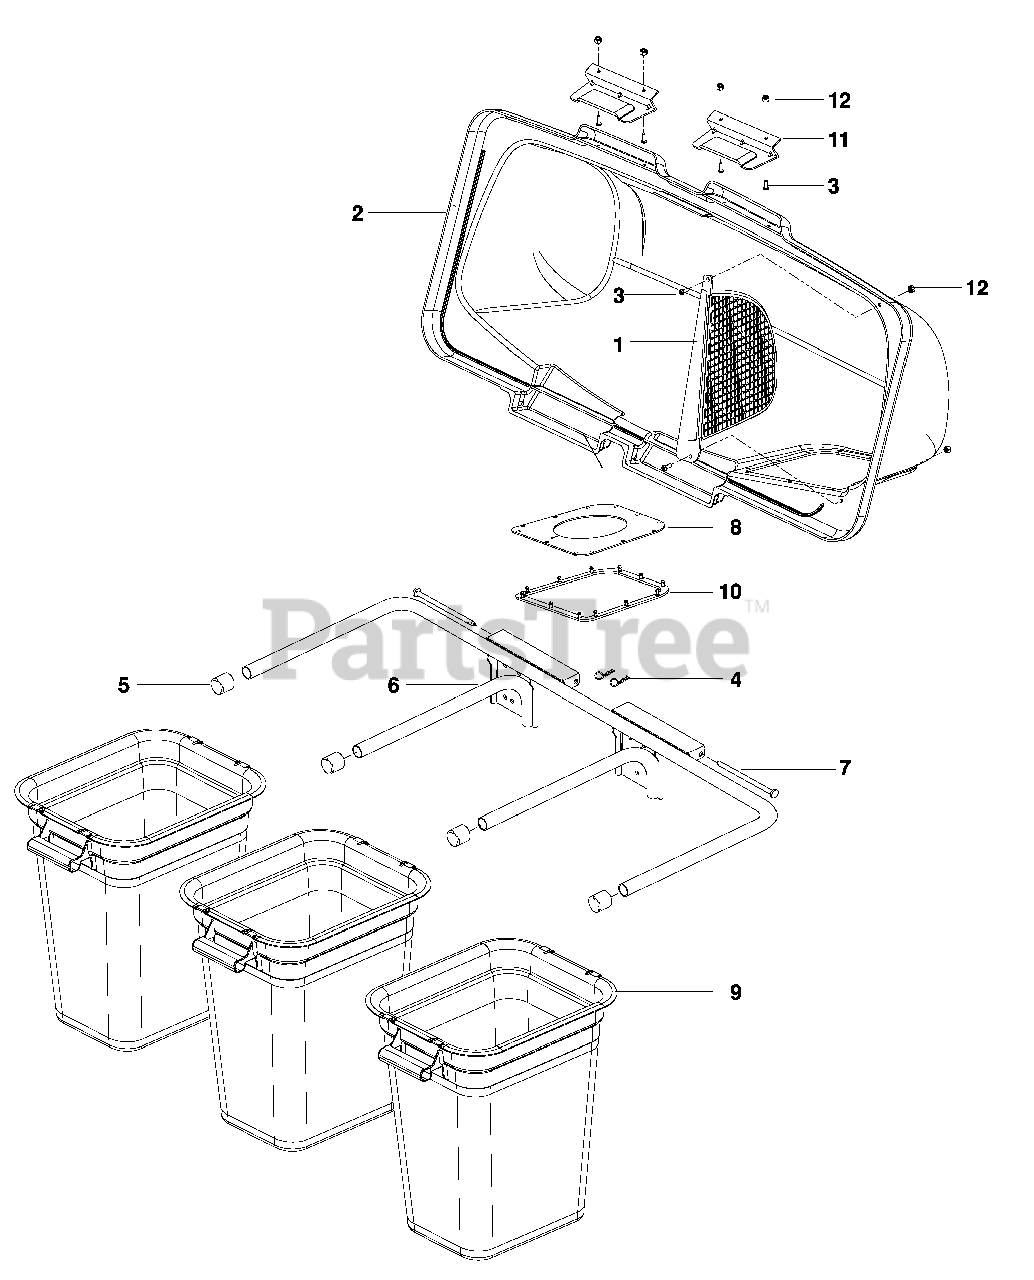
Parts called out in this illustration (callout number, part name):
1	SCREEN, COVER
3	SCREW #10-24 x 5/8
5	PLUG, TUBING END
6	BAGGER, fRAmE
7	PIN, HINGE
8	SEAL, COVER
9	CONTAINER, SOfT BAG
10	GASKET, COVER
11	HANDLE, BAGGER COVER
12	NUT #10-24 CROWNLOCK
